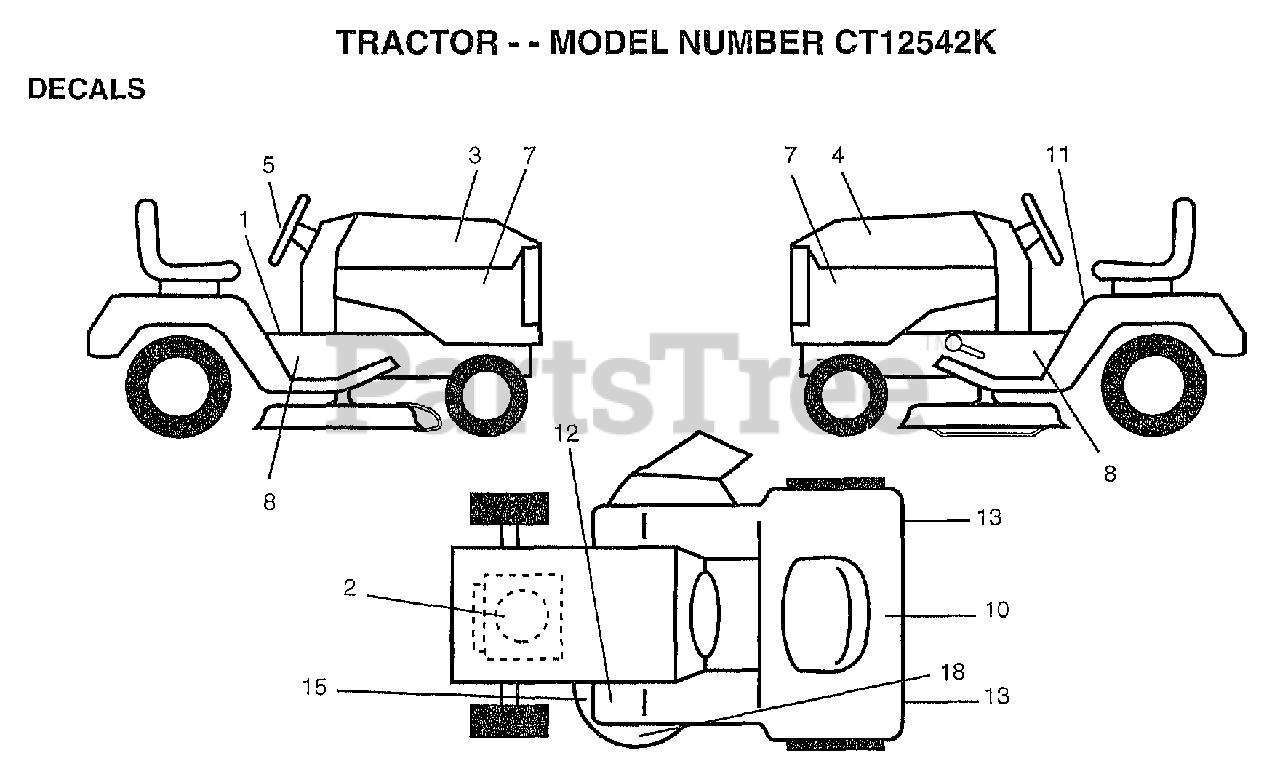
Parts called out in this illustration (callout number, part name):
1	"DECAL DASH,OPER."
2	DECAL, HP ENGINE
3	DECAL HOOD RH
4	"DECAL HOOD,LH"
5	DECAL INST STG WH
7	"DECAL PANEL,SIDE"
8	"DECAL CHASSIS 42"""
10	DECAL.BATRY.3-3908
11	"DECAL DANGER,FEND"
13	REFLECTOR-TAIL YT
15	DECAL
